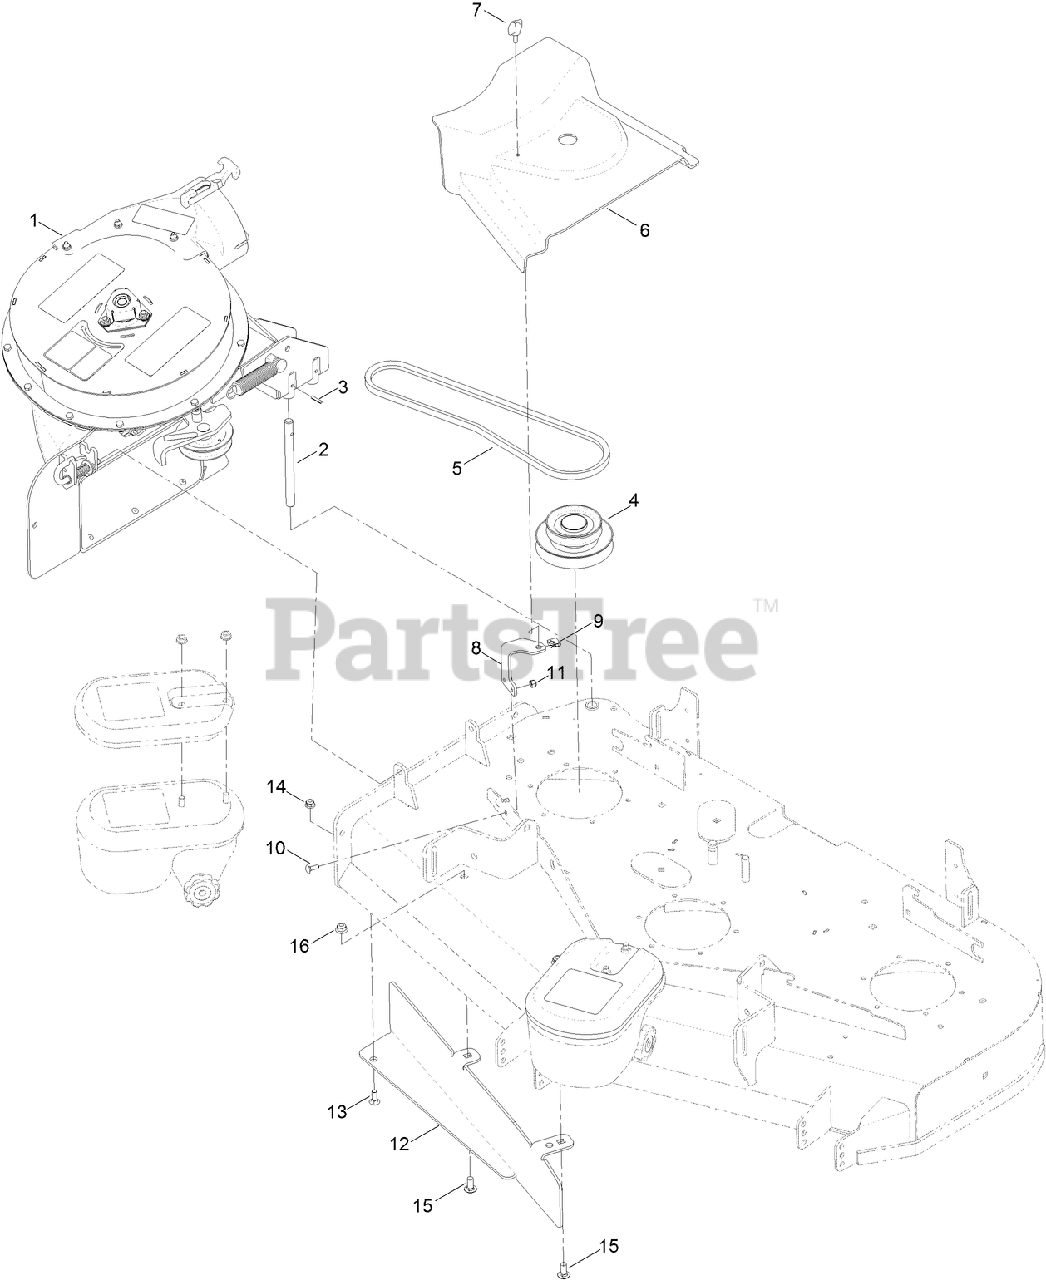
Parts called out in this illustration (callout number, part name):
1	BLOWER ASM
2	SHAFT-CATCHER, GRASS
3	PIN-ROLL
4	DRIVE-JACKSHAFT
5	BELT-V
6	COVER-BELT
8	BRACKET-COVER, BELT
9	NUT-SPEED
10	BOLT-CARR
11	NUT-LOCK, NI
12	BAFFLE-BAGGER
13	SCREW-CARR
14	NUT-HF, NI
15	SCREW-CARR
16	NUT-HF, NI
